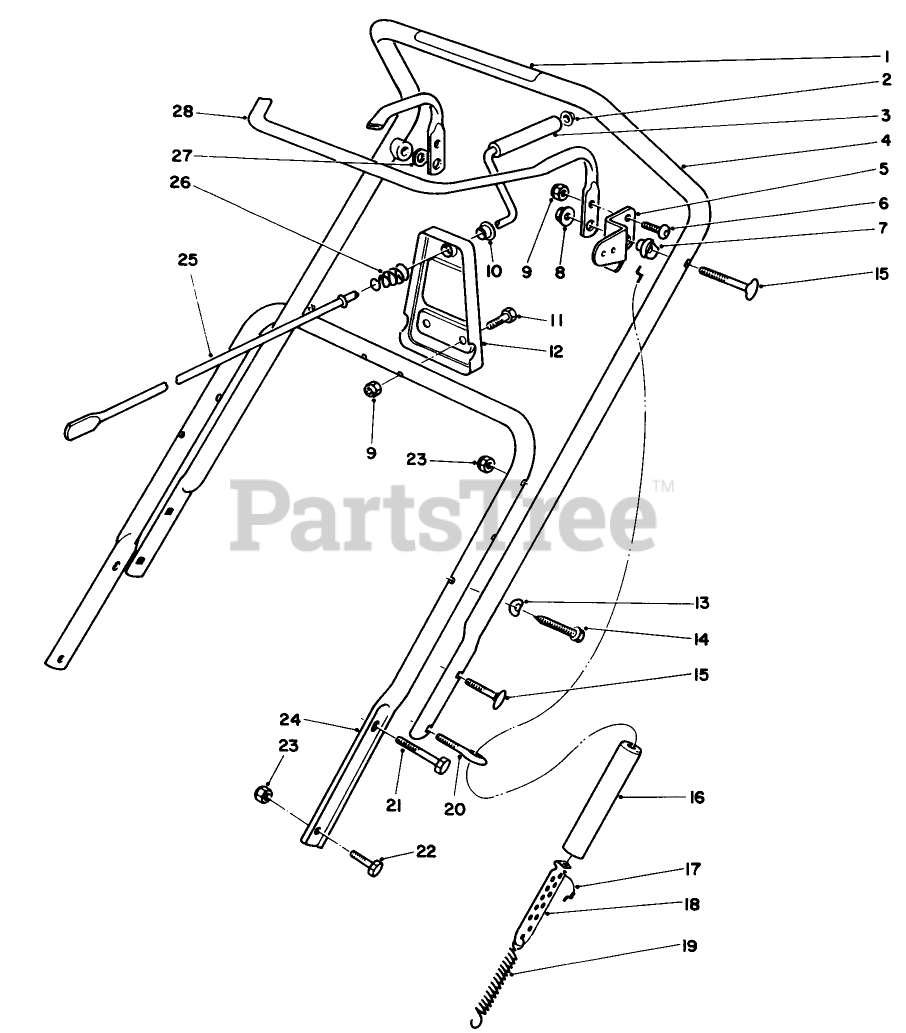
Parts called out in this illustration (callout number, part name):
2	NUT-PUSH
6	SCREW-HSBH
7	SPACER-BAR, CONTROL
8	NUT-ACORN
9	NUT-LOCK, NI
11	SCREW-HH
13	WASHER
16	COVER-SPRING
17	CABLE-CLUTCH
18	ADJUSTER-CABLE
19	SPRING-EXTENSION
20	BOLT-EYE
21	SCREW-HH
22	SCREW-HH
23	NUT-LOCK, NI
25	ROD-CRANK, CHUTE
26	SPRING-COMPRESSION
27	WASHER
